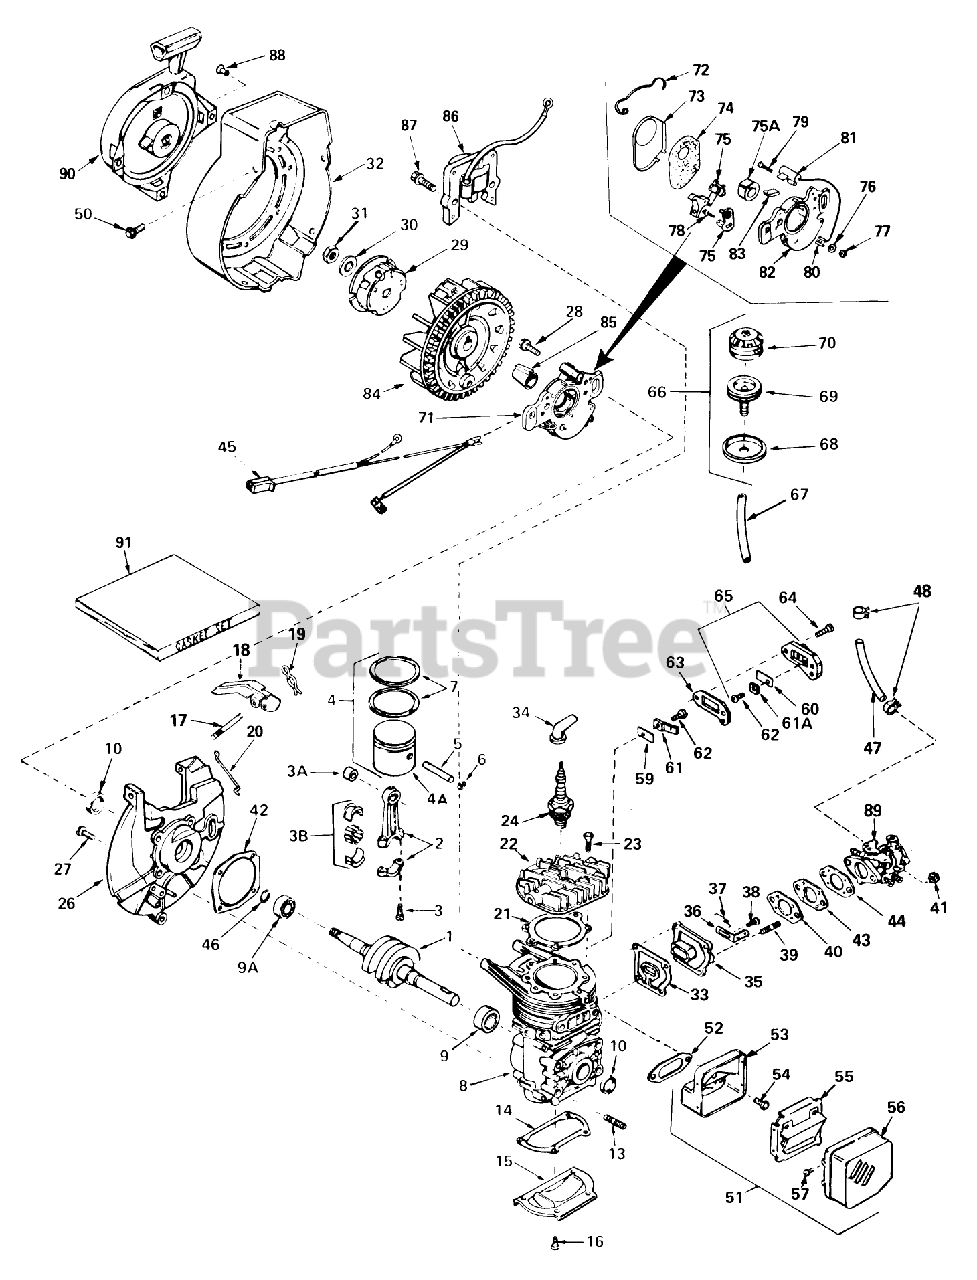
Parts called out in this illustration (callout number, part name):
1	Crankshaft
2	Rod Assembly, Connecting (Incl. #3, 3A 3B)
3	Bolt-Rod, Connecting
3A	Bearing-Cartridge
3B	Bearing Liner Set Needle
4	Piston, Pin Ring Assy. (Incl. Ref. #6 thru 9)
4A	Piston
5	Pin, Piston
6	Ring-Retaning
7	Ring Set
9	Bearing-Cartridge
9A	Bearing-Ball
10	Seal-Oil
14	Gasket, Cover
15	Plate, Cover
16	Screw (T-25, 10-24 x 1/2)
17	Shaft, Air Vane
18	Vane Assy., Air
19	Clip,Air Vane
20	Link, Governor
21	Gasket, Head
22	Head-Cylinder
23	Screw (T-30, 1/4-20 x 3/4)
24	Head Adjustment Knob
26	Base Assy., Blower Housing (Incl. Ref. #10 17)
27	Screw
28	Screw, Hex Washer Hd.
29	Cup-Starter
30	Washer-Spring
31	Nut-Flywheel
32	Housing-Blower
33	Gasket, Port
34	Cover-Spark Plug
35	Adapter, Cover
36	Lever, Adjusting
37	Spring, Adjusting Lever
38	Screw
40	Gasket, Carburetor 1/8" thick)
41	Locknut
42	Gasket, Shroud Base
43	Spacer
44	Gasket, Carburetor (1/16"thick)
45	Harness, Wire
46	Ring, Retaining
47	Line-Fuel (8.62)
48	Clamp-Line, Fuel
50	Screw-Hex, Hd.
51	Muffler Assembly (Incl. #53-57)
52	Gasket-Muffler
53	Base-Muffler
54	Screw
55	Baffle, Muffler
56	Cover, Muffler
57	Screw
59	Reed, Compression Release
60	Reed, Compression Release
61	Plate, Reed Hold Down
61A	Plate, Reed Hold Down
62	Screw
63	Gasket, Compression Release
64	Screw
65	Cover Assy., Compression release (Incl. Nos. 60, 61A 62)
66	Primer Assy.
67	Line, Primer
68	Retainer, Primer Bulb
69	Body, Primer
70	Bulb-Primer
71	Stator Plate Assy. (incl. Nos. 107, 111 thru 118 120)
72	Spring Breaker Box
73	Cover-Dust
74	Gasket Dust
75	Breaker Assy.
75A	Cam, Breaker
76	Washer
77	DECAL
78	Breaker Screw
79	Condenser Screw
80	Terminal, Ground
81	Condenser
82	Stator Plate
83	Felt,Cam Wiper
84	FIywheel
85	SHIELD
86	Lamination Coil Assy. (Incl. No. 42)
87	Screw
88	Rivet, Pop (3/1 6" dia.)(Can be purchased locally)
89	Carburetor (Incl. Ref. #44) (Used on Type 1601 1601A)
90	Starter-Rewind
91	Gasket Set (Incl. items marked *)
